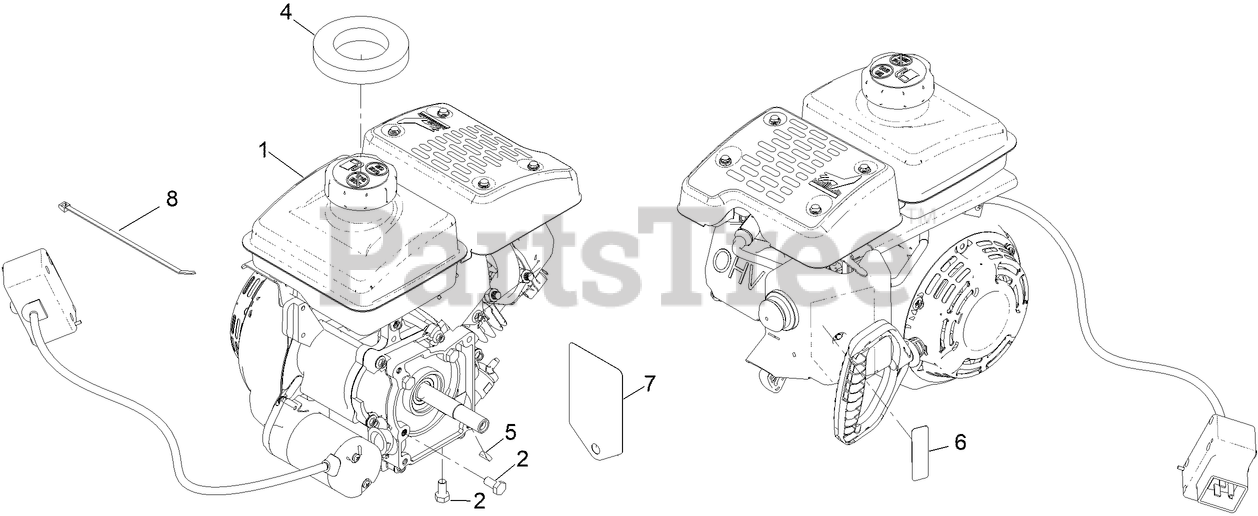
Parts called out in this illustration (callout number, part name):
1	ENGINE-LC156FDS
2	SCREW-HH
4	SEAL-TANK
5	KEY-WOODRUFF
6	DECAL-CONTROLS, ENGINE
7	TAG-HANG, 4-CYCLE
8	TIE-CABLE
